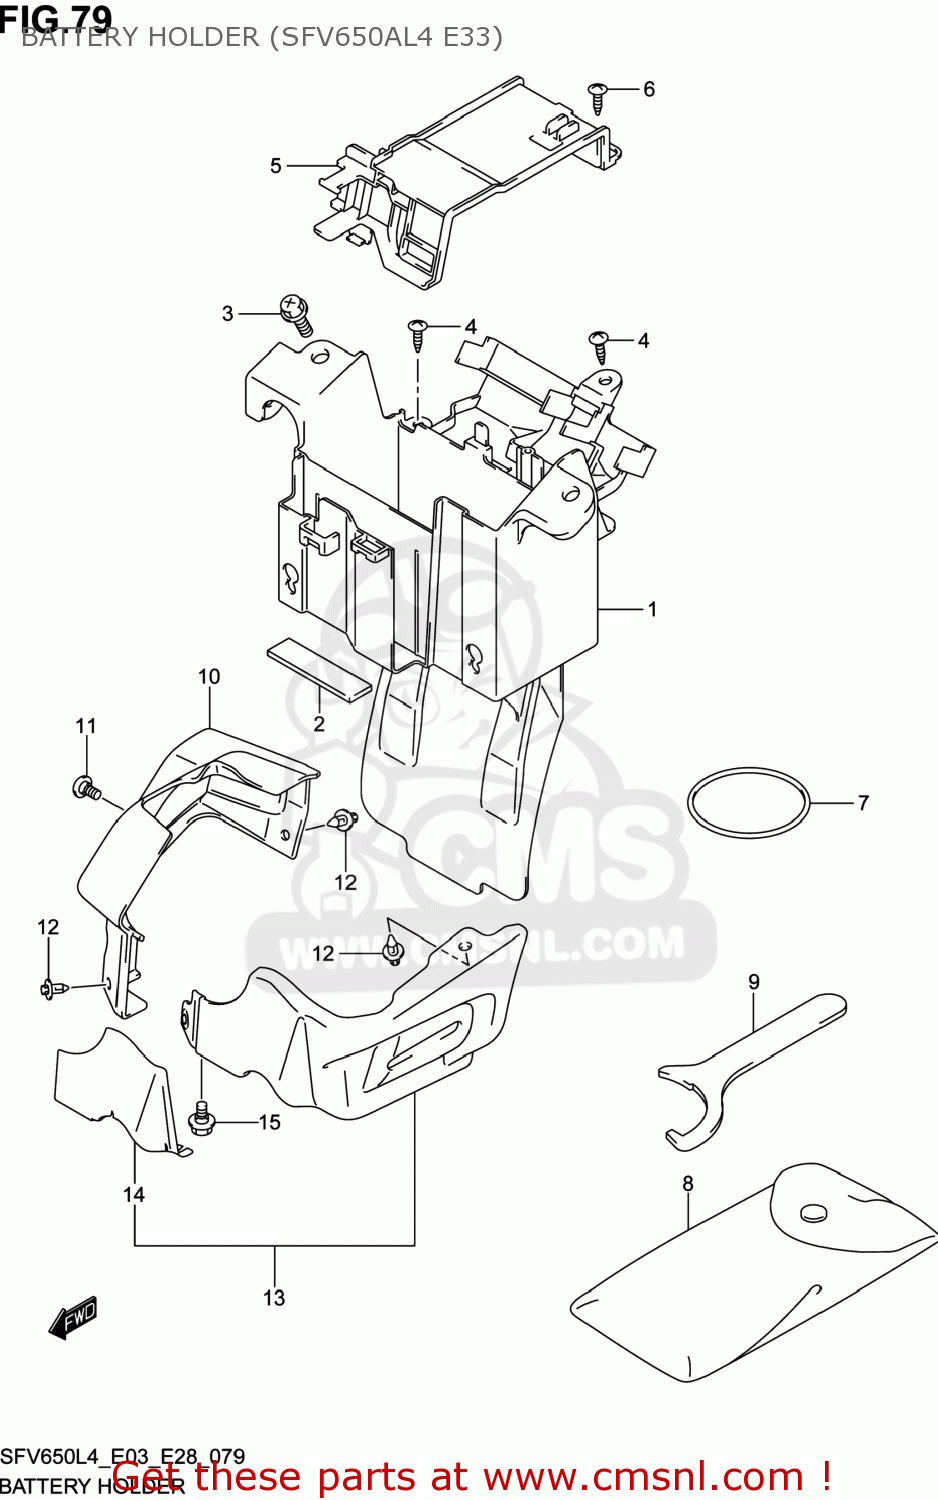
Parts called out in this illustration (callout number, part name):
1	HOLDER,BATTERY
2	CUSHION,FR FENDER
3	BOLT(6X16)
4	SCREW
5	LID,BATTERY HOLDER
6	SCREW
7	O RING(D:3.5,ID:56.5)
8	TOOL ASSY
9	CLAMP
10	COVER,HYDR ABS UNIT,R
11	SCREW(6X12)
12	CLIP(BLACK)
13	COVER,HYDR ABS UNIT,L
14	SHIELD,ABS UNIT COVER,L
15	BOLT(6X12)
